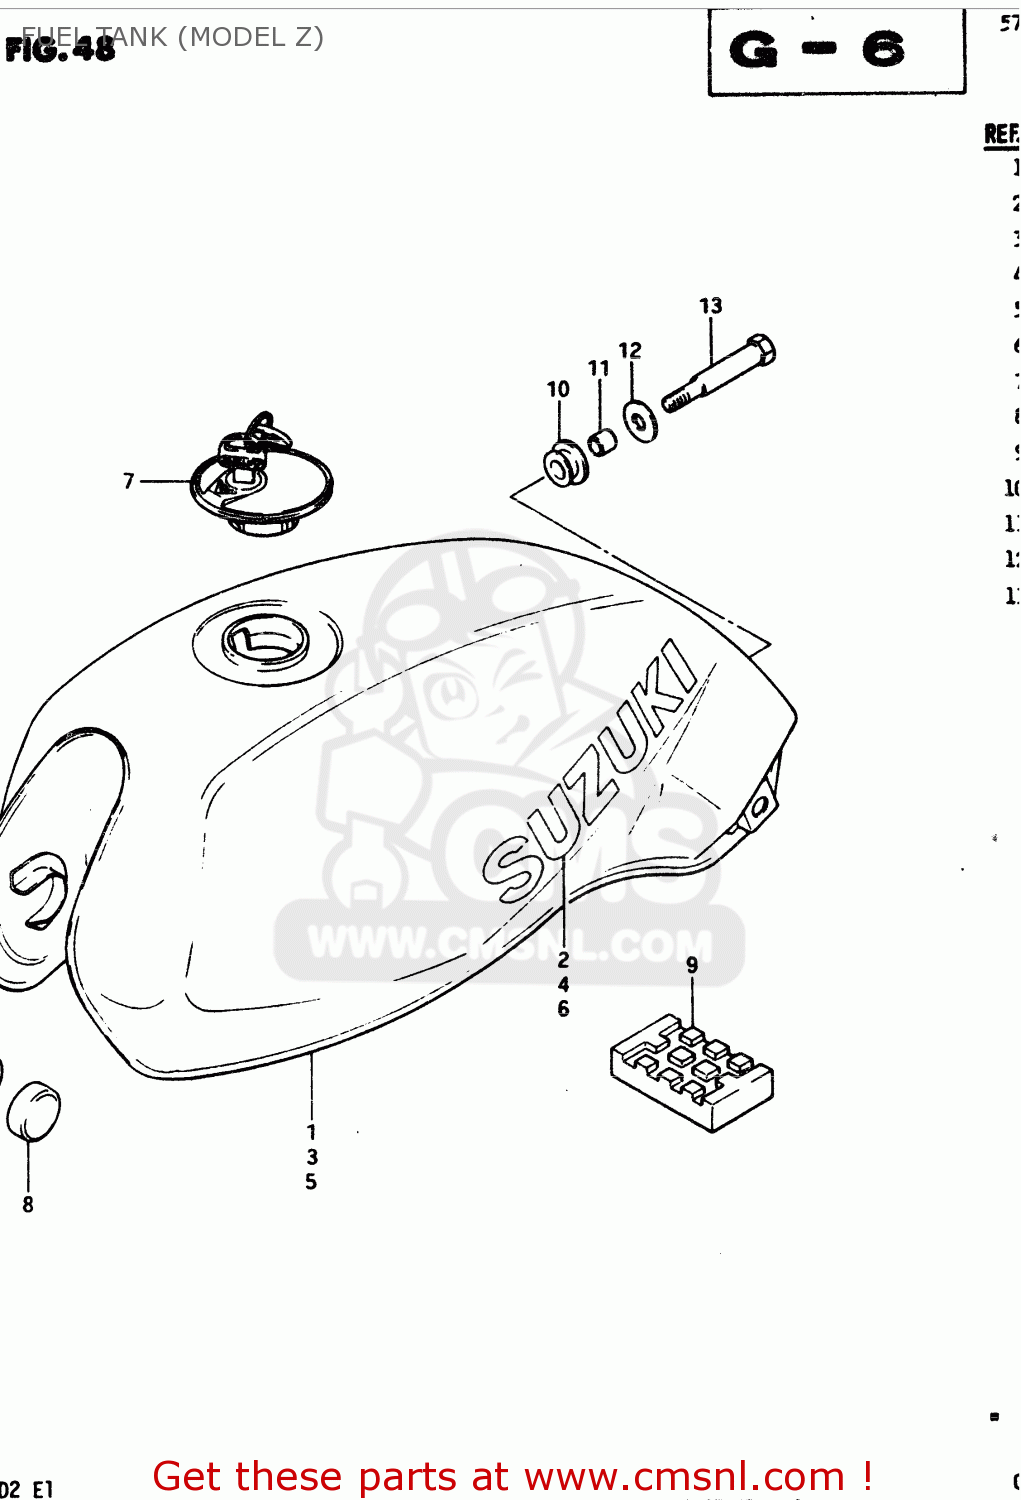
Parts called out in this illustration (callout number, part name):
1	TANK ASSEMBLY,FUEL
2	EMBLEM(SILVER)
3	TANK, FUEL (SILVER)
4	EMBLEM(ORANGE)
5	TANK, FUEL (BLACK)
6	EMBLEM(SILVER)
7	CAP SET,FUEL TANK
8	CUSHION
9	CUSHION,FUEL TANK CTR
10	CUSHION
11	SPACER (6.8X10X10)
12	WASHER (6.5X29X1.6)
13	BOLT(6X60)
